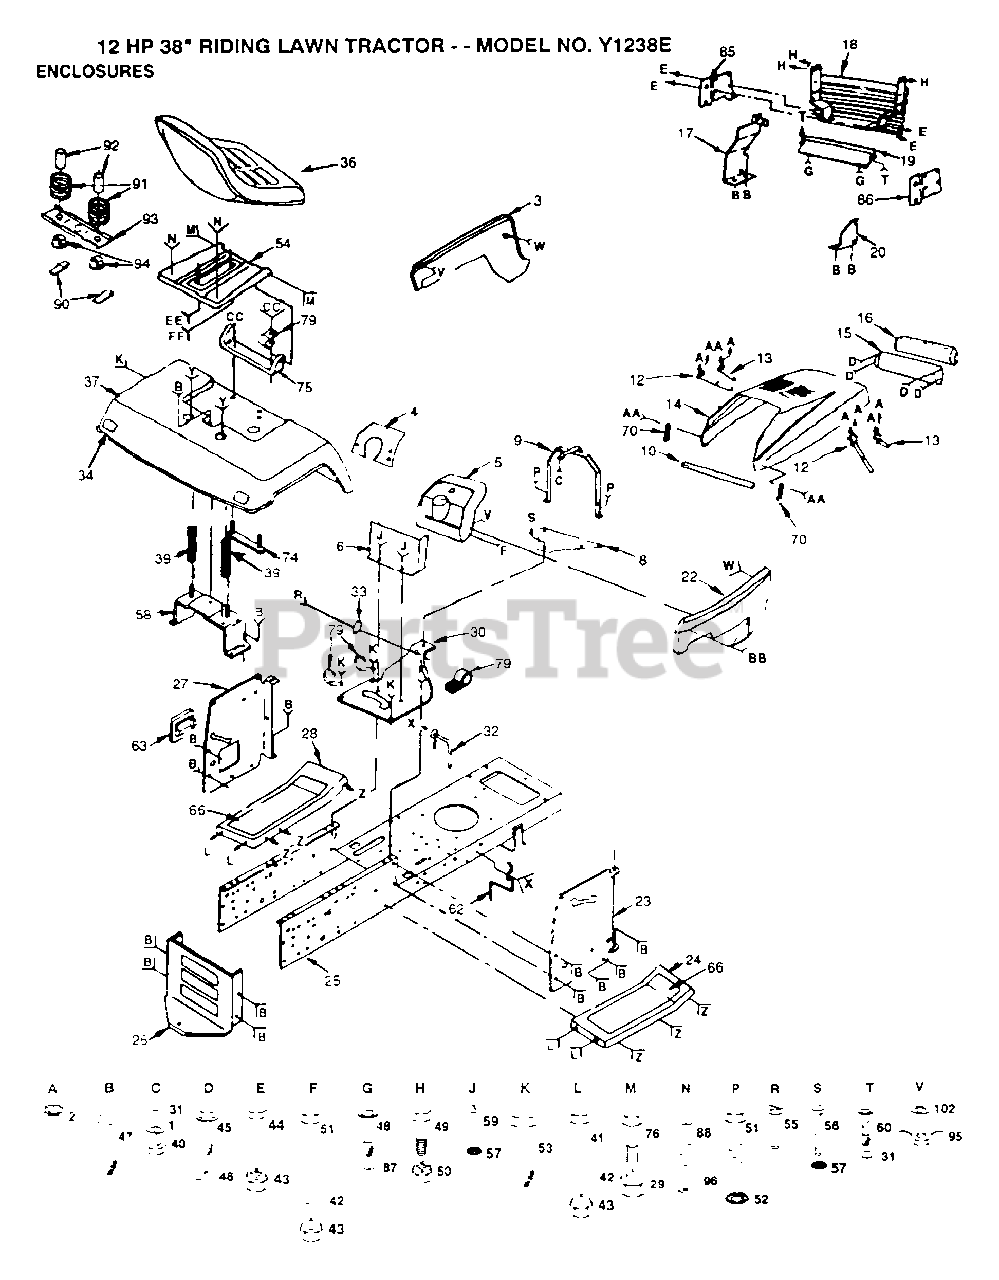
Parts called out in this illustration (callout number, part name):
1	LOCKWASHER
2	NUT
6	DASH ASSY LT
9	SUPPORT ASSY LT
10	FOAM-STRIP LT
16	LENS LT
19	"STRAP,GRILL "
20	SUPPORT LH YTH
23	PANEL DASH RH YT
31	WASHER PM
32	BELT GUIDE
34	REFLECTOR-TAIL YT
39	SPRING COMPRESSIO
42	WASHER
44	BOLT
46	"""J"" FASTENER LT"
47	SCREW
52	NUT
53	SCREW LT
56	BOLT
59	SCREW
60	SCREW HEX CRT
62	BELT GUIDE
63	COVER ACCESS
66	PAD FOOTREST T
70	HOOD LATCH T
79	CLIP T
85	SUPPORT LH YTH
86	SUPPORT RH YTH
87	WASHER
88	BOLT
90	STRIP FORM
91	SPRING
92	SPACER SPLIT
93	BRKT SWITCH
94	BUSHING
102	LOCKWASHER GT
